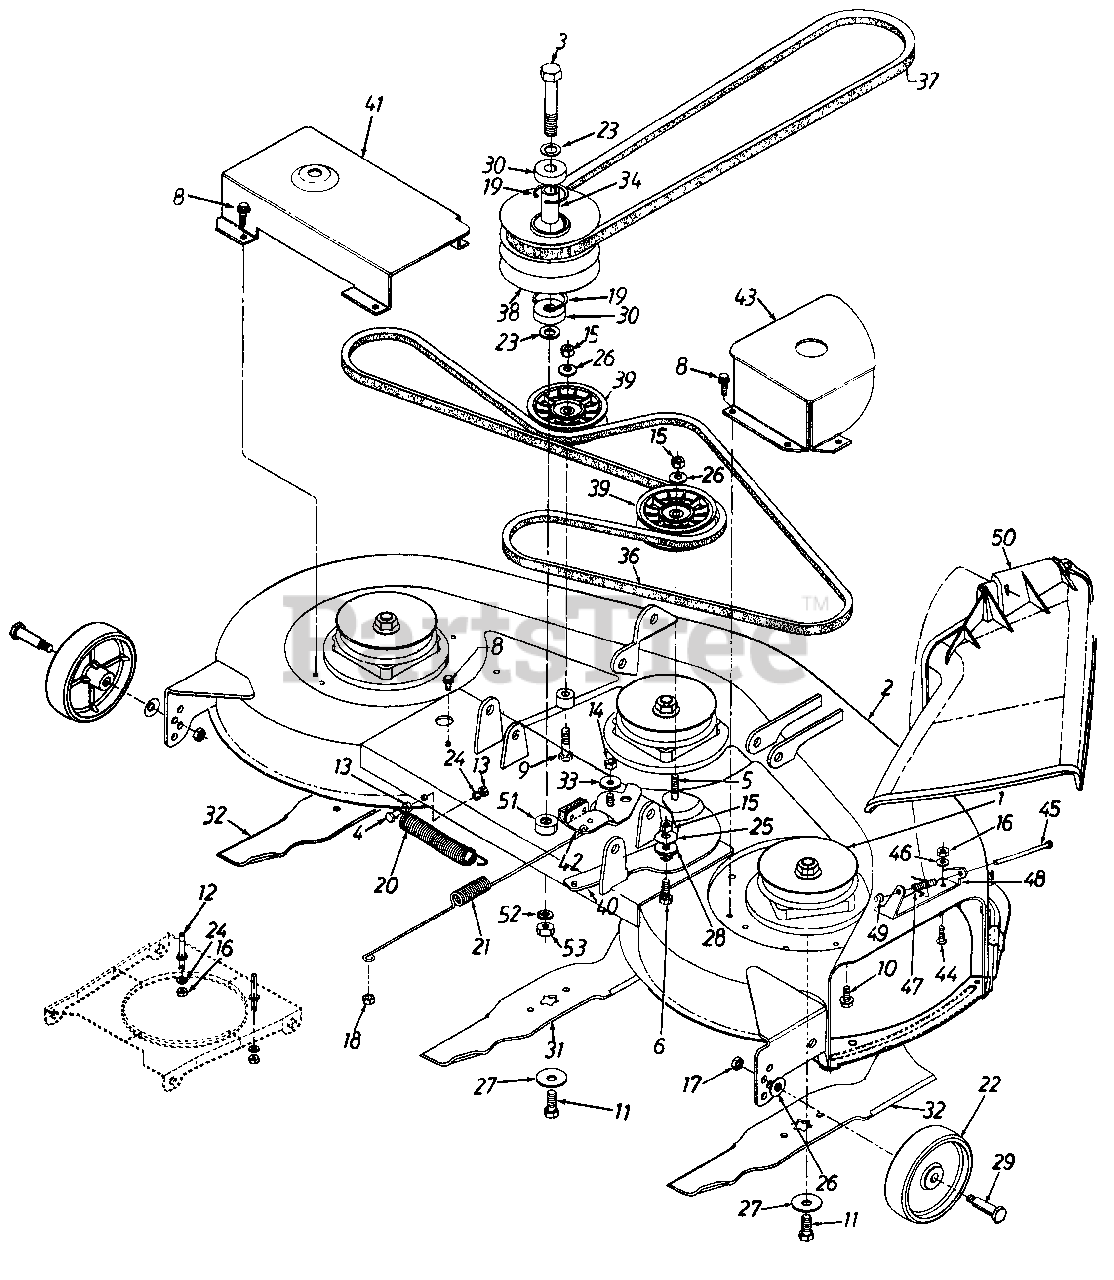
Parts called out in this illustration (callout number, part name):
1	Blade Spindle Ass'y.
4	Hex Bolt 1/4-28 x 1.25" Lg.
5	Hex Bolt 3/8-24 x 1.5" Lg.
6	Hex Bolt 3/8-24 x 1" Lg.
8	Hex Wash. Hd. TT-Tap Scr. 1/4-20 x .5" Lg.
9	Hex Bolt 3/8-24 x 2" Lg.
10	Hex Flange Bolt 5/16-24 x .75" Lg.
11	Hex Patch L-Bolt 7/16-20 x 1" Lg.
12	Belt Guard Pin
13	Hex Nut 1/4-28 Thd.
14	Hex Ins. L-Nut 5/16-24 Thd.
15	Hex Nut 3/8-24 Thd.
16	Hex Nut 1/4-20 Thd.
17	Hex Top Jam Nut 3/8-16 Thd.
18	Hex Patch L-Nut 5/16-18 Thd.
19	Int. Snap Ring
20	Ext. Spring .88" O.D. x 6.17"
21	Ext. Spring .788" O.D. x 15.5"
22	Deck Wheel
23	Fl-Wash .635" I.D. x 1" O.D. x .06"
24	L-Wash. 1/4" I.D.
25	Bell-Wash. 3/8" x 1.125" x .062"
26	Bell-Wash. 3/8" x .87" x .064"
27	Bell-Washer
28	Shoulder Spacer .625" I.D. x .169"
29	Shld. Bolt .498" x 1.525"
30	Ball Brg .625" I.D. x 1.574" 0.D. x .47"
31	High Lift Blade 14.88" Lg.
32	High Lift Blade 16.28" Lg.
33	Shoulder Spacer
34	Spacer .635" l.D. x .088" O.D.
36	V-Belt
37	V-Belt
38	Pulley Double Deck 5" O.D.
39	Flat Idler Pulley 3.5 O.D.
42	Deck Brake Brkt. Ass'y.
44	Hex Bolt 1/4-20 x .62" Lg.
45	Hinge Pin
46	Bell-Wash. 1/4" 1.D.
47	Torsion Spring
48	Hinge Mtg. Brkt.
49	Push Nut
50	Chute Ass'y. Comp.
51	Spacer .635" I.D. x 1" O.D.
52	L-Wash. 5/8" I.D.
53	Hex Nut 5/8-18 Thd.
